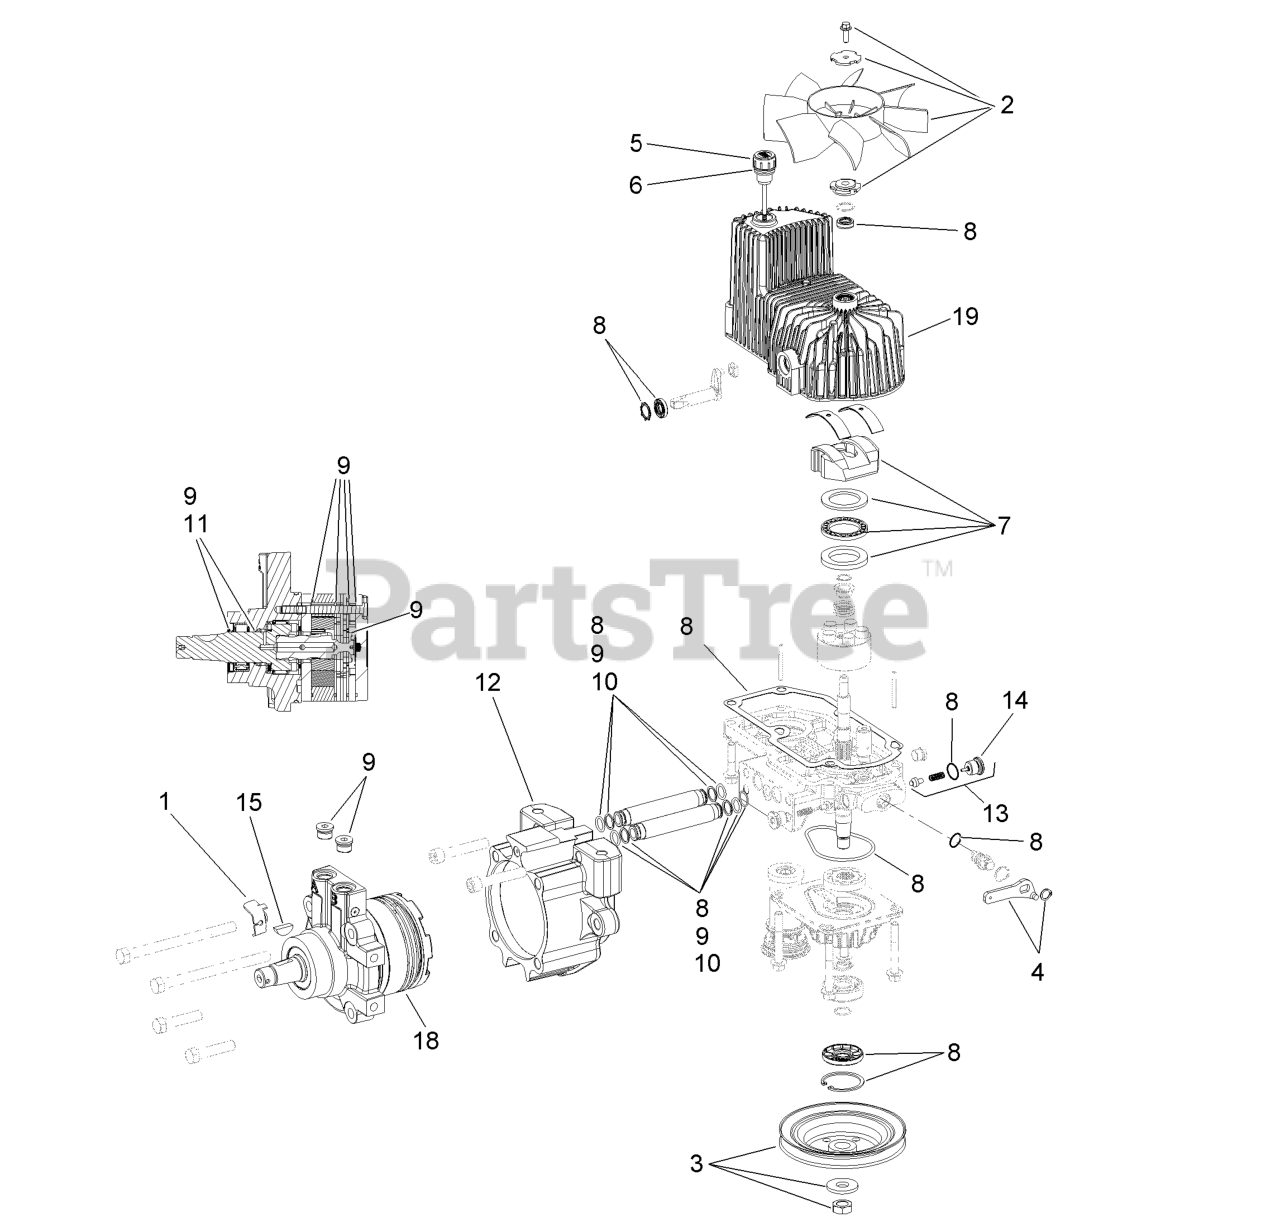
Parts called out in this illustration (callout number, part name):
1	BRACKET-ANCHOR, CABLE
2	FAN KIT
3	PULLEY KIT
4	HANDLE-BYPASS VALVE, HYDRO
5	DIPSTICK-HYDRO W/GASKET
6	GASKET-DIPSTICK, HYDRO
7	SWASH BLOCK KIT
8	PUMP SEAL KIT
9	MOTOR SEAL KIT
10	TUBE SEAL KIT
11	OUTPUT SHAFT SEAL KIT
13	CHECK VALVE ASM
14	PLUG-CHECK (W/O-RING)
15	KEY-WOODRUFF
19	HOUSING-HYDRO, LH
